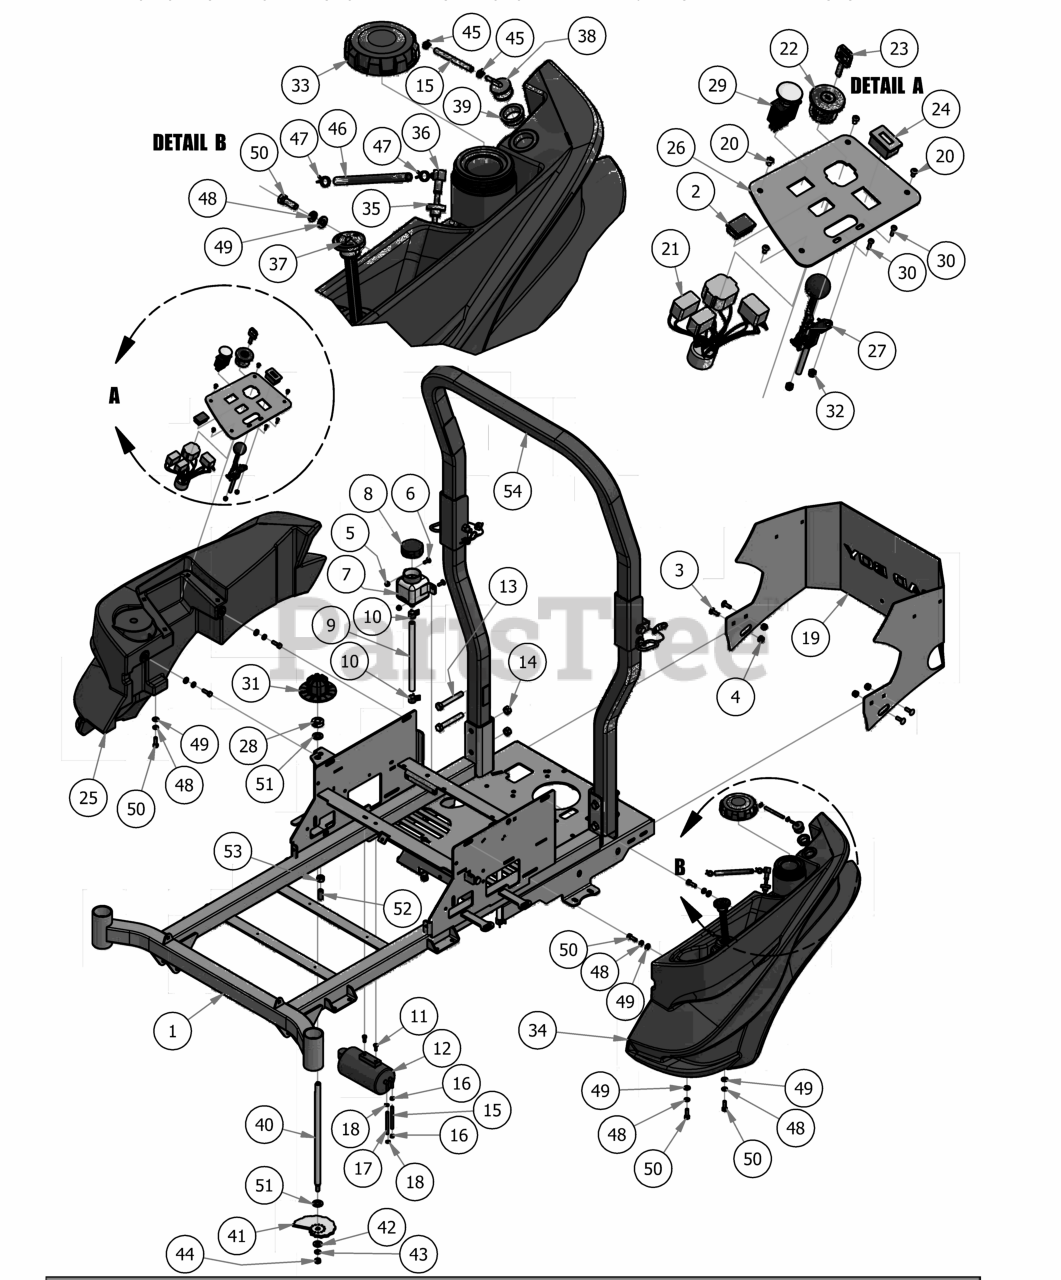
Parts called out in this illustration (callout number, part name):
1	2018 Compact Outlaw Frame
3	5/16" x 1" Carriage Bolt
4	5/16-18 Nylon Flange Nut
5	1/4" Nylock Nut
6	1/4" x 3/4" Carriage Bolt
7	350ml Expansion Tank
8	Hydraulic Tank Cap
9	3/8" Clear Hose
10	3/8" Hose Clamp
11	M6-1.0 X 16MM Hex Bolt
12	Carbon Canister
13	1/2-13 x 3 1/2 GR 5 Hex Bolt
14	1/2" Center Lock Nut
15	1/4" Vinyl Tubing
16	1/4" Hose Clamp
17	3/16 Vinyl Tubing
18	3/16" Vinyl Hose Clamp
19	2017 ZT Rear Plate
20	10-32 x 3/8" Button Socket Head Bolt
21	Universal Wire Harness
22	Ignition Switch
23	Ignition Key
24	Tachometer
25	Right Side Console
26	Control Panel
27	Throttle Lever Assembly
28	5/8" Split Collar
29	PTO Switch
30	10-24 X 5/8 BS Button Head Bolt
31	MZ/ZT Deck Height Dial
32	10-24 Nylon Insert Locknut Zinc Orange Nylon
34	Left Fuel Tank
35	Pick-Up Grommet
37	Fuel Gauge w/Grommet
38	Rollover Valve
39	Rollover Valve Grommet
40	2017 Deck Height Dial Rod ZT
41	2017 MZ/ZT Cam Plate
42	3/8" Flat Washer
43	3/8" Lock Washer
44	3/8" Fine Threaded Jam Nut
45	3/16 Vinyl Clamp
46	1/4" Fuel Line Hose
47	1/4 Fuel Hose Clamp
48	5/16" Lock Washer
49	5/16" Flat Washer
50	5/16" x 1" Bolt
51	.630 ID x 1.122 OD x .142 THK Plastic Washer
52	Dial Rod Plunger
53	1/2" Hex Nut
